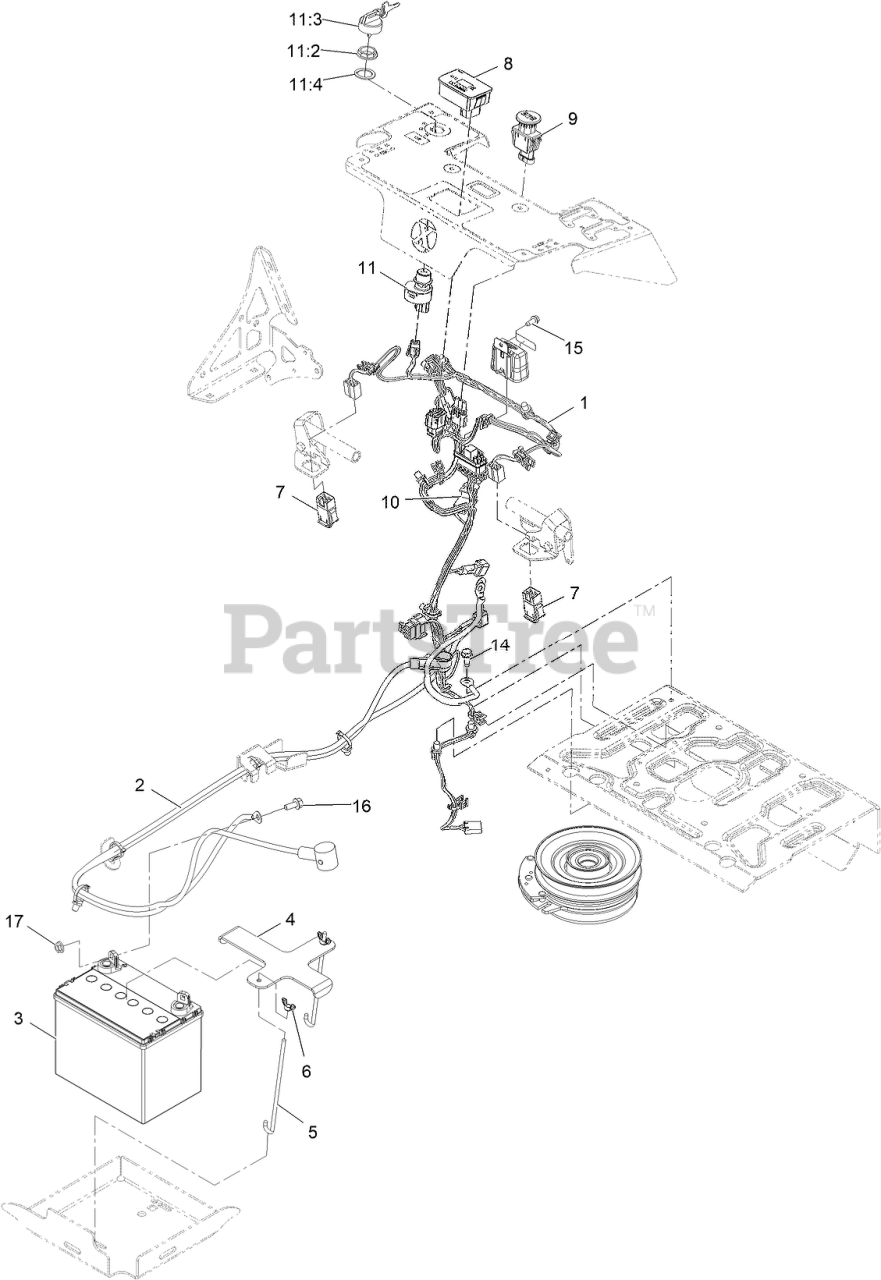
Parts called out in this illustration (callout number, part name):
1	HARNESS-WIRING
2	HARNESS-BATTERY
3	Battery
4	BRACKET, BATTERY HOLD DOWN
5	BOLT-HOLDDOWN
6	WINGNUT
7	SWITCH-DELTA
8	Module-Hour Meter
9	SWITCH-PTO, SEALED
10	SWITCH-BAIL
11	IGNITION SWITCH ASM
11:2	NUT-MOUNTING
11:3	IGNITION KEY SET
11:4	WASHER-BACKUP
14	SCREW-THD ROLL, HWH
15	SCREW-HWH
16	SCREW-HHF
